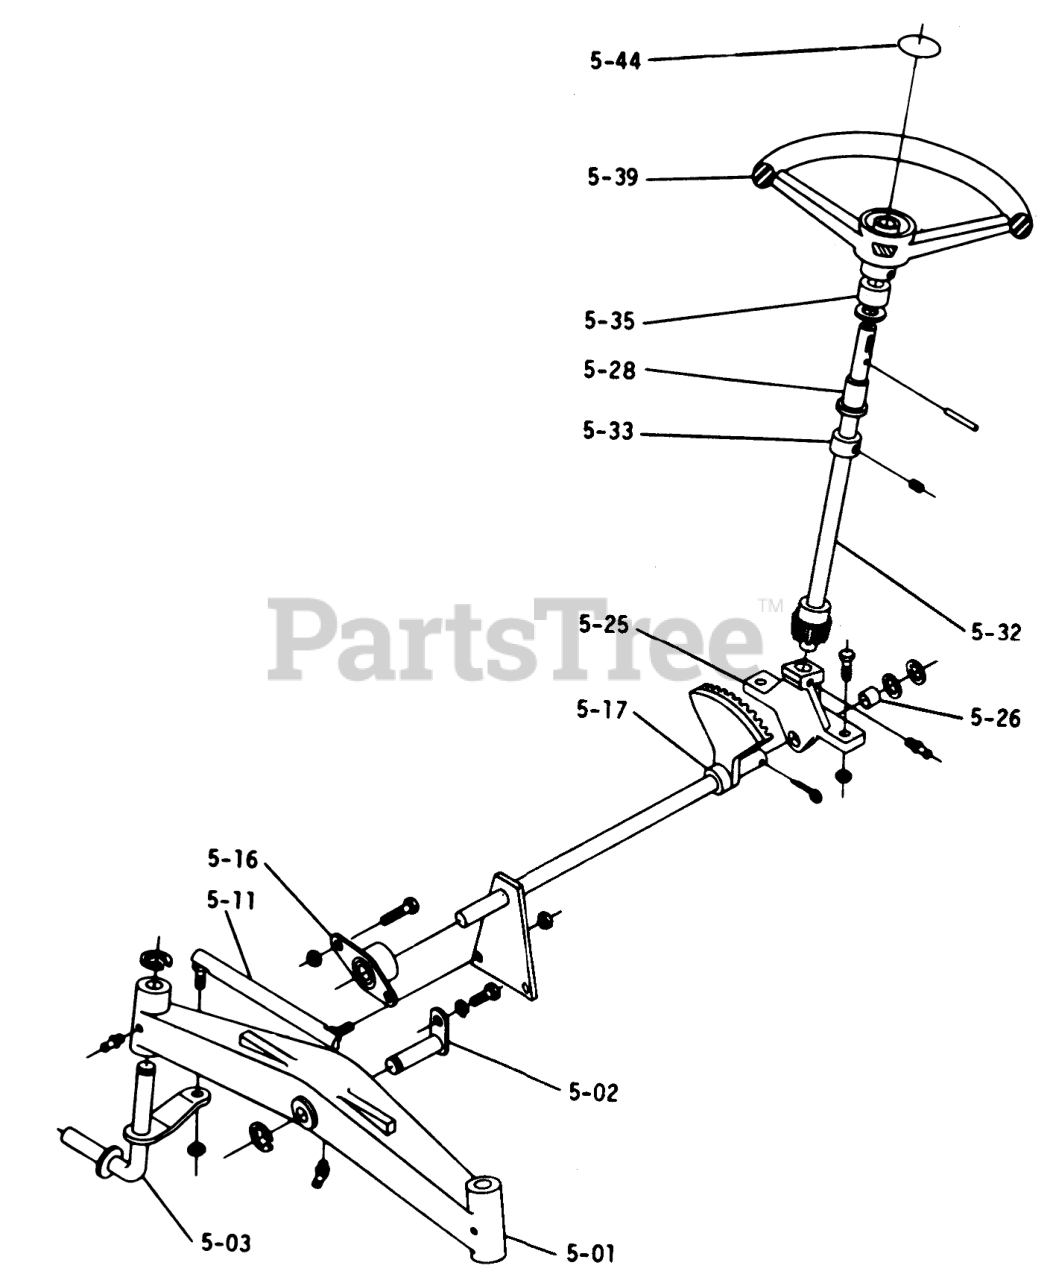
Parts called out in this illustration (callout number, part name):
5-01	AXLE-FRONT
5-02	PIN AND PLATE ASM
5-03	R.H. Spindle
5-11	Tie Rod RH
5-16	BEARING-FLANGED
5-17	Lower Steering Shaft
5-25	Support
5-26	BEARING-BRONZE
5-28	BEARING
5-32	Upper Steering Shaft
5-33	Collar
5-35	Collar
5-39	STEERING WH 13" SOFT
5-44	STEERING WHEEL INSE
